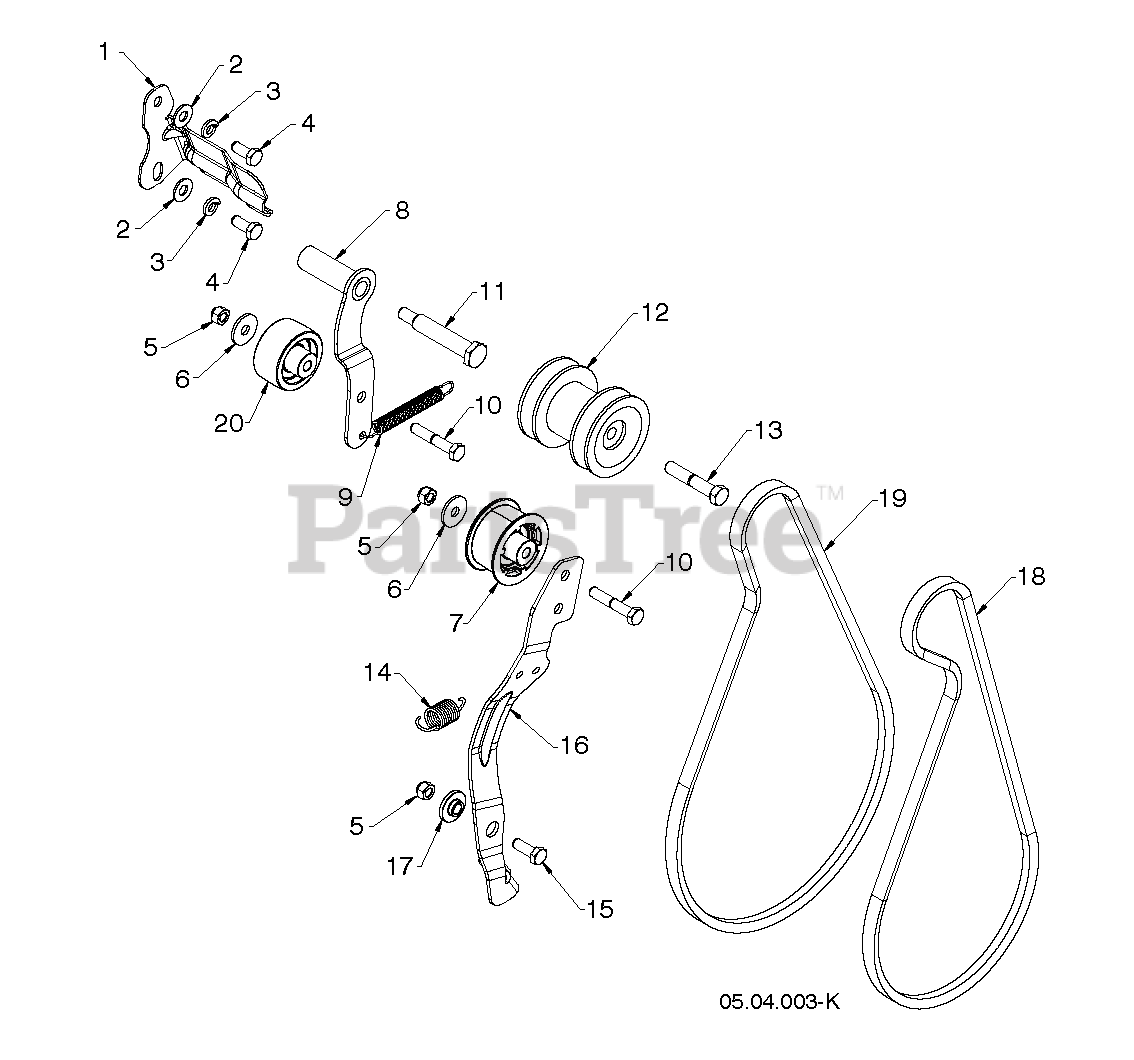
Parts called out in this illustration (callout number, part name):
1	BRACKET.BELT.KEEPER.004.BZP
2	WASHER M
3	LOCKWASHER
4	SCREW 5/16-24 X .75 GR5
5	NUT.71038.31-18.HEX.NYLOCK
6	STEEL WASHER
7	PULLEY,IDLER,2.00 W SPA
8	ARM IDLER DRIVE WELDMENT_HOT
9	SPRING RETURN IDLER ARM
10	BOLT, HEX 5/16-18X1-3/4
11	BOLT 5/16-24X2.25 HEX HEAD SHO
12	PULLEY.ASM.IMPELLER/DRIVE
13	BOLT.BLADE
14	SPRING RETURN, IDLER ARM, IMPE
15	BOLT
16	BRACKET ARM.IDLER.IMPELLER ARM
17	BUSHING.BRAKE.ARM
18	BELT.AUGER.HI.CRANK
19	BELT.DRIVE.HI-CRANK
20	PULLEY.IDLER.FLANG.2.O/SPACER
